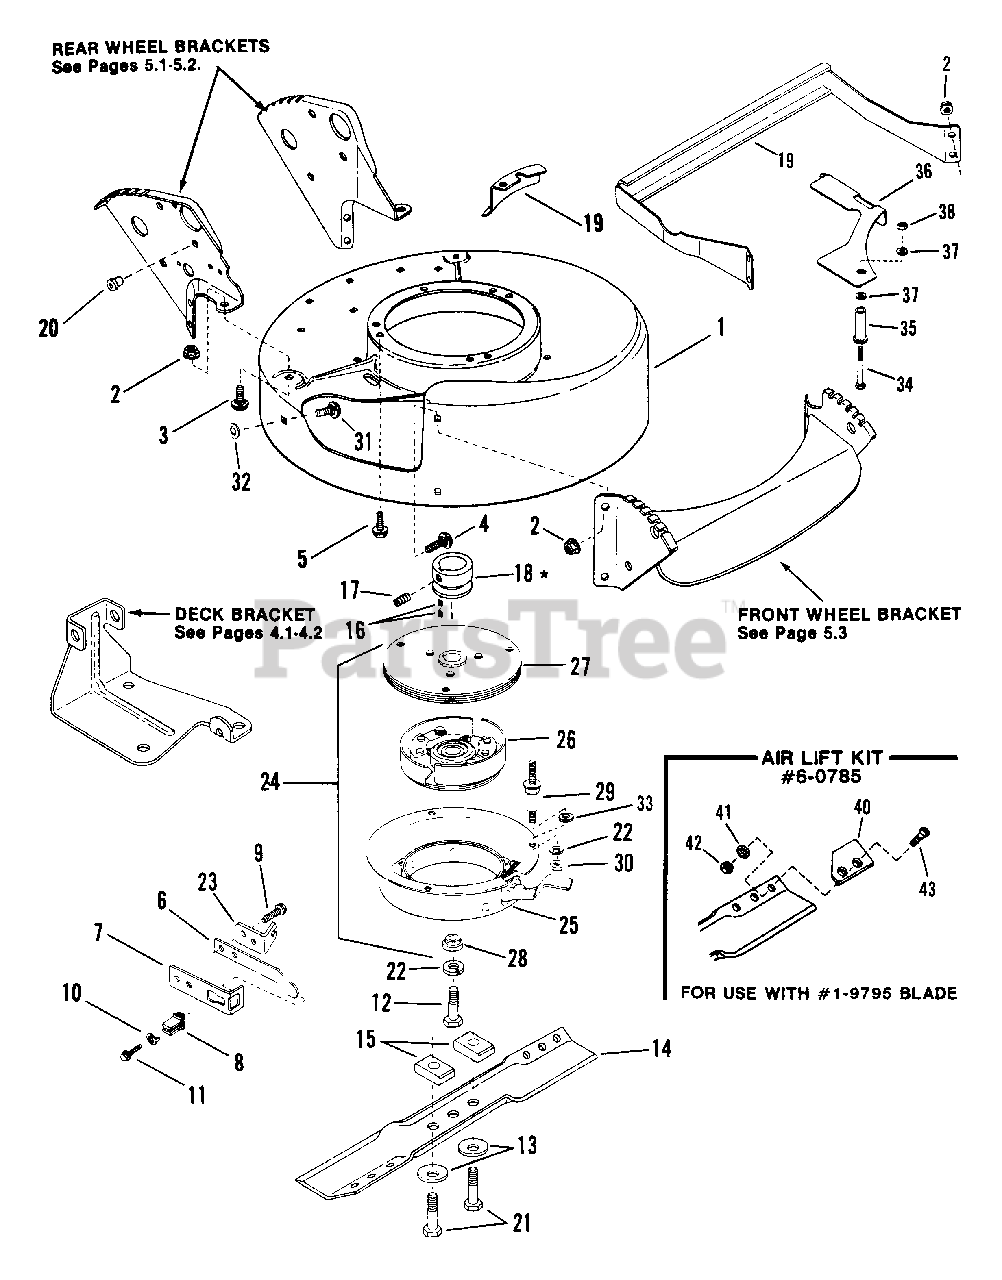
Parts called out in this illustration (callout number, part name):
1	DECK, Mower
1-9795	Blade
2	NUT, Hex Flanged Lock
3	BOLT, 5/16-18 x 1/2" Short Neck Carriage Gr. 5
4	BOLT, Bolt 5/16-18 x 1-1/8" Short Neck Carriage
5	SCREW, 3/8-16 X 1" Self-tapping (Engine Mounting)
6	SPRING, Wheel Bracket Type Interlock
6-0785	Air Lift Kit
7	BRACKET, Wheel Bracket Type Interlock
8	INSULATOR, Interlock
9	SCREW, 1/4-20 x 1/2" Hex Self-tapping
10	WASHER, No. 8 Tab Int. Tooth Lock
11	SCREW, #8-18 x 3/4" Hex Head Machine
12	SCREW, 3/8-24 x 2.0" Hex Head Cap
13	WASHER, Cone
14	BLADE, Cutter
15	SPACER, Blade
16	KEY, Hi-Pro
17	SCREW, 5/16-18 x 5/16" Hex Socket Set
18	PULLEY, Engine (25mm I.D. x 2-1/8" O.D.)
19	STRUCTURE, Fender (Euro)
20	BUSHING, Interlock Wire
21	SCREW, 3/8-16 x 1-3/4" Hex Head Cap
22	LOCKWASHER, 3/8 Split
23	BRACKET, CABLE-BBC
24	ASSEMBLY, Blade Clutch
25	ASSEMBLY, Bowl & Brake
26	ASSEMBLY, Clutch Bearing
27	ASSEMBLY, Flywheel
28	WASHER, Blade
29	STAND-OFF
30	NUT, 3/8-16 Hex Flange Lock
31	BOLT, 5/16-18 x 1" Short Neck Carriage
32	RETAINER, 5/16 Bolt
33	WASHER, 3/8" Flat
34	BOLT, 5/16-18 x 2-1/4" Hex Flange Lock
35	BUSHING
36	COVER, Belt
37	LOCKWASHER, 5/16 Split
38	NUT, 5/16-18 Hex
40	LIFT, Air
41	WASHER, 5/16 Internal Tooth Lock
42	NUT, 5/16-24 Hex
43	SCREW, 5/16-24 x 21/32" Machine
